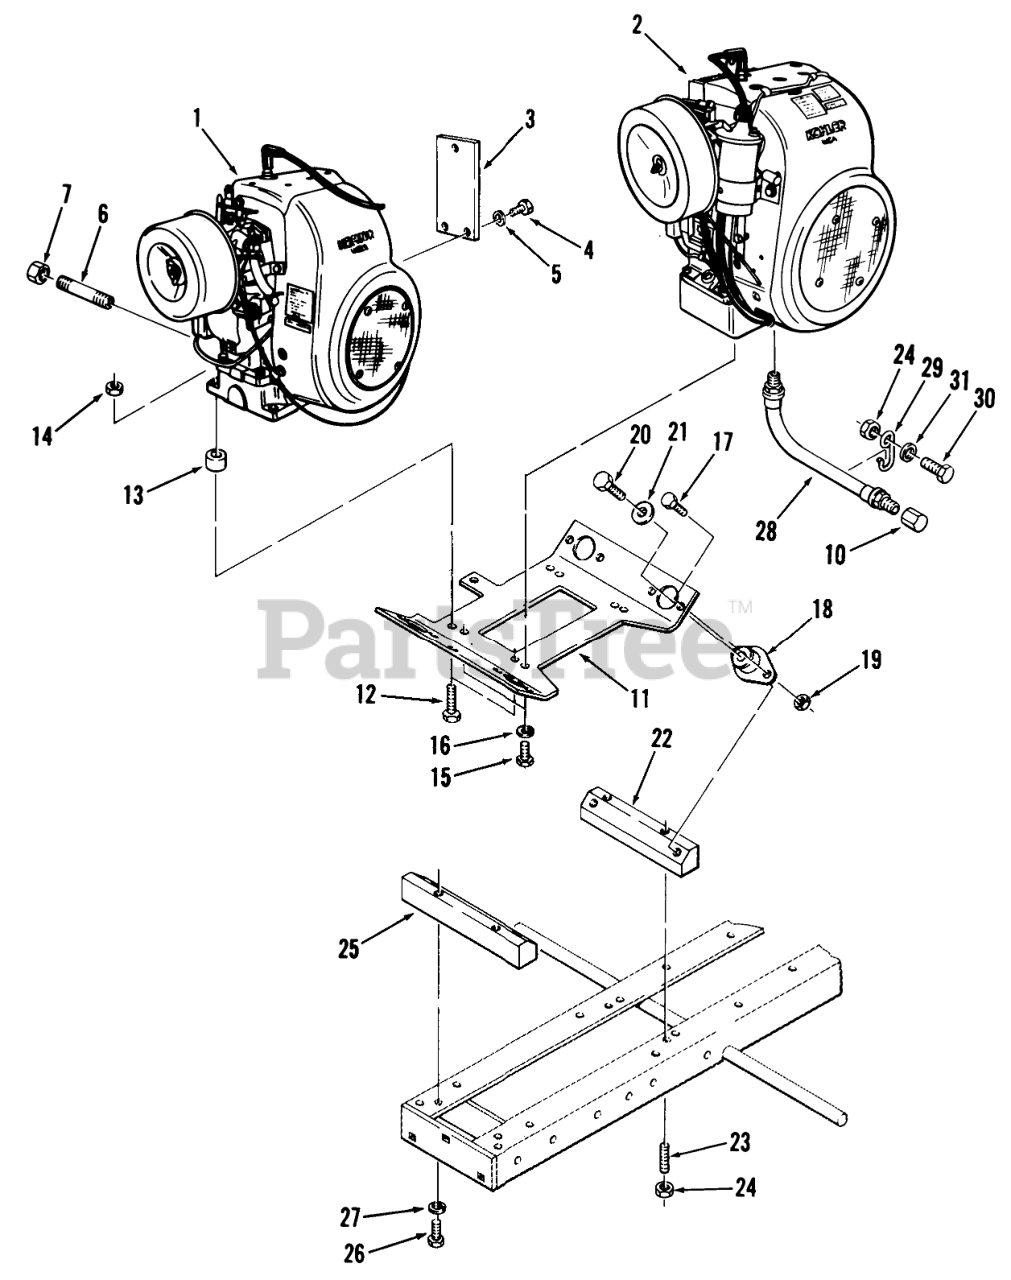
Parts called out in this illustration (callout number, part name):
1	Engine-8HP Kohler K-1815 Spec PS-30743D
2	Engine-14 HP Kohler K-321AS Spec 60373
2	Engine-10 HP Kohler K-241AS Spec 46812
2	Engine-12HP Kohler K-301A5 Spec PS-47762D
3	PLATE COIL & SOL MTG
4	BOLT
5	LOCKWASHER
6	Nipple 1/2"
7	CAP-PIPE 1/2 IN
10	CAP 1/4 PIPE
11	Engine Cradle
12	Bolt
13	SPACER
14	Nut
15	Bolt
16	LOCKWASHER
17	H H C S
18	MOUNT-ISOLATION
18	Isolation Mount C-85
19	Nut
20	Bolt
21	Washer
22	MOUNT-BLOCK-REAR
23	SET SRW 3/8X16-1 3/4
24	Nut
25	Engine Mounting Block-Front
26	BOLT
27	LOCKWASHER
28	ASM-HOSE
29	RETAINER-HOSE
30	Bolt
31	Washer
